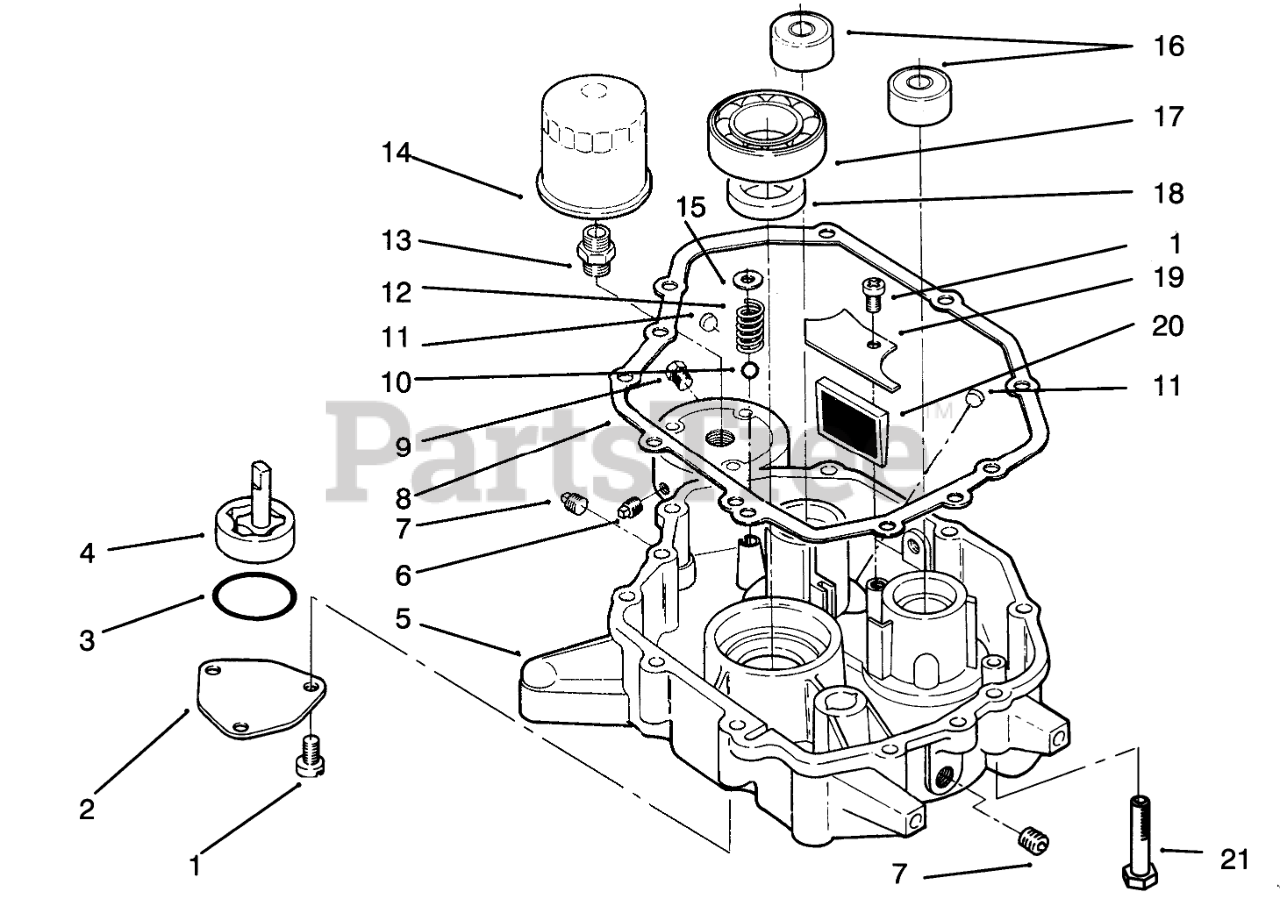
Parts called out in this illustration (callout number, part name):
1	SCREW-M6 X 14
2	COVER-OIL PUMP
3	RING-O
4	PUMP-OIL
5	BASE-0IL
6	PLUG-COUNTERSUNK HD
7	PLUG - SQUARE HEAD
8	Gasket
9	PLUG-HEX HD
10	BALL-BEARING
11	Plug
12	Spring
13	ADAPTER
14	FILTER
15	RETAINING-RING
16	BRNG-BALL BAL SHFT L
17	BRNG-BALL CRANKSH L
18	SEAL-OIL CRNKSHFT UP
19	COVER
20	SCREEN
21	SELF-TAP BOLT SP M8
